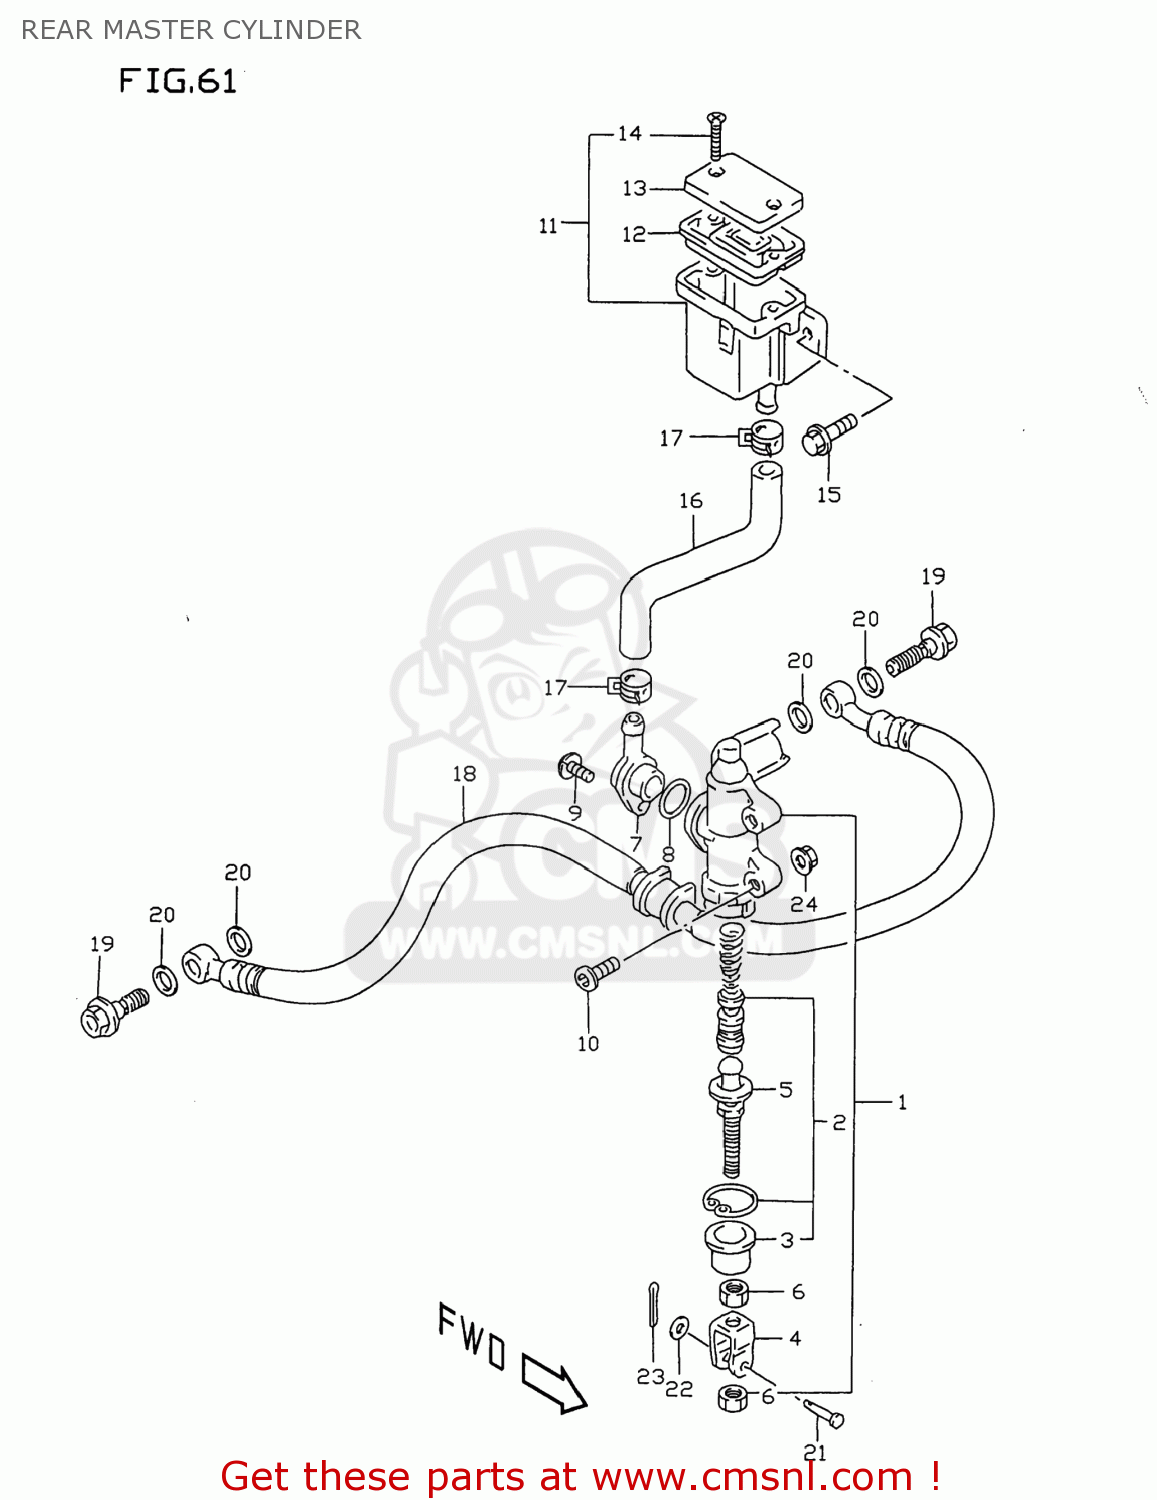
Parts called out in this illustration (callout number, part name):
1	CYLINDER ASSY,RR MASTER
2	PISTON/CUP SET
3	BOOT
4	YOKE
5	ROD,PUSH
6	NUT
7	CONNECTOR
8	O RING
9	SCREW
10	SCREW(6X30)
11	TANK ASSY,RESERVOIR
12	DIAPHRAGM
13	CAP
14	SCREW
15	BOLT
16	HOSE,RESERVOIR TANK
17	CLIP
18	HOSE,RR BRAKE
19	BOLT UNION
20	WASHER(10X15X1.5)
21	PIN
22	WASHER
23	PIN
24	NUT
